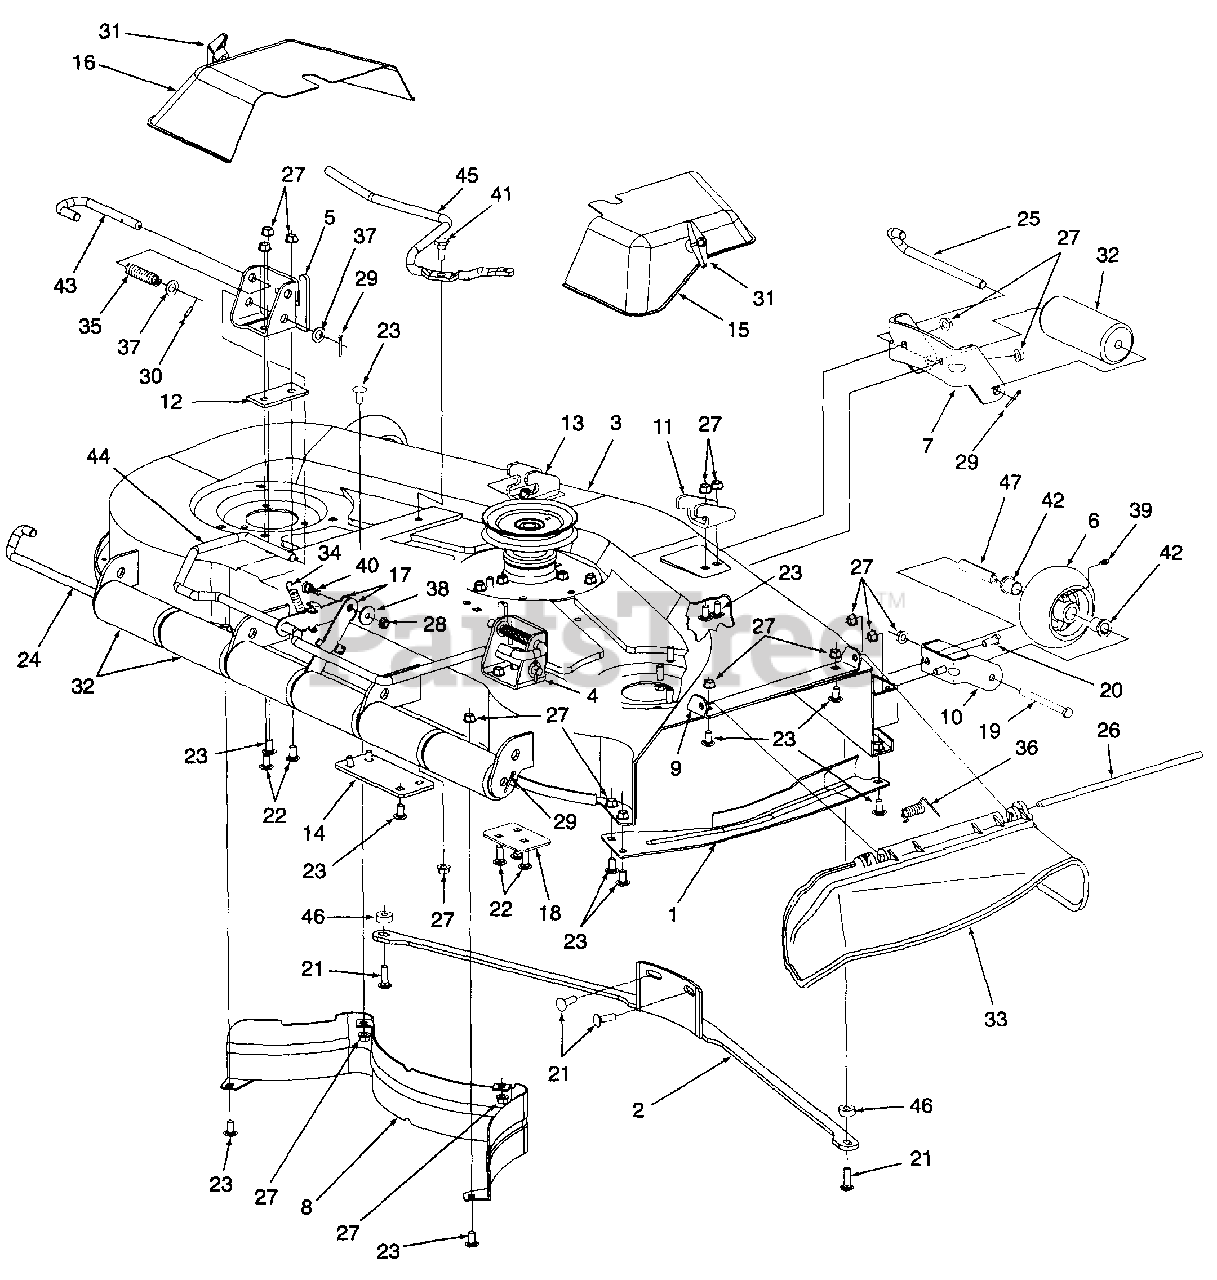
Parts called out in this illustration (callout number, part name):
20	Screw, Hex Cap, 3/8-16 x .88 GR5
21	Bolt, Carriage, 3/8-16 x 1.25 GR5
22	Bolt, Carriage, 3/8-16 x 1.0 GR5
23	Bolt, Carriage, 3/8-16 x .75 GR5
24	Pin, Roller
25	Pin, Roller, 1/2 x 7.31
26	Hinge Pin
27	Nut, Hex Flange Lock, 3/8-16
28	Nut, Hex Flange Lock, 5/16-18
29	Pin, Cotter 1/8 x 1.0
30	Pin, Spirol Spring, 3/16 x 3/4
31	Knob, Wingnut, 5/16-18
32	Roller, Front & Rear
33	Deflector, Plastic Chute
34	Spring, Extension
35	Spring, Compression
36	Spring, Torsion
37	Washer, Flat, .536 x .93 x .05
38	Washer, Flat, .344 x 1.125 x .12
39	Grease Fitting
40	Bolt, Shoulder, .437 x .268:5/16-18
41	Bolt, Shoulder, .50 x .267:3/8-16
42	Bearing, Flange
43	Pin, Mower Support
44	Rod, Deck Support
45	Rod, Idler Spring Mtg
46	Spacer, .406 x 1.0 x .38
47	Spacer, Wheel
